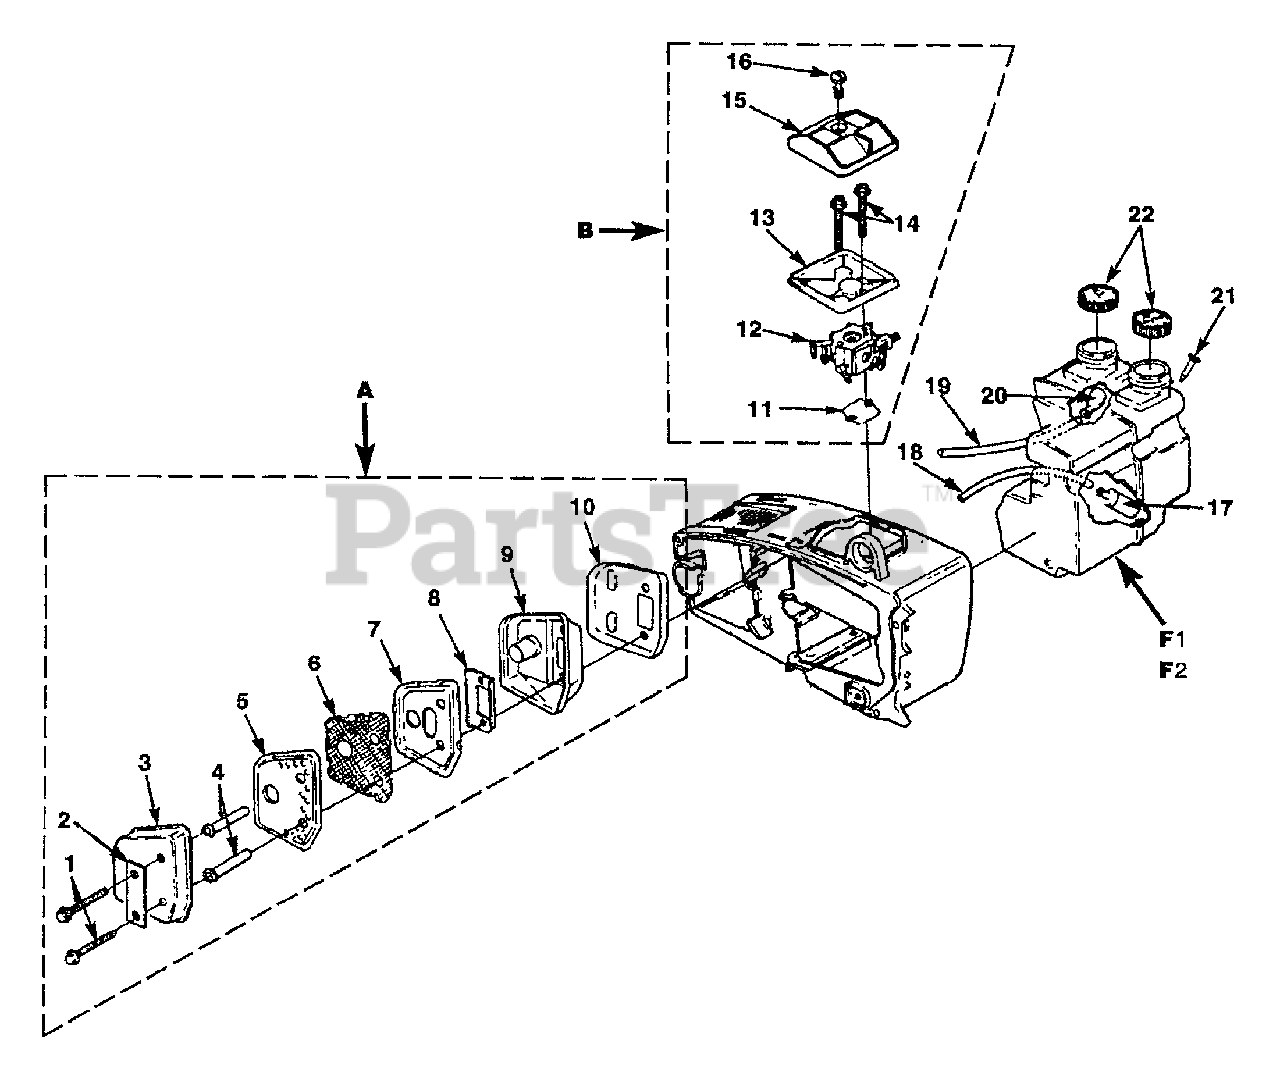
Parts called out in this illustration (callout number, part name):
1	SCREW-Mach. Sems Hex (10-24 x 2 1/16")
2	BRACKET-Muffler
3	CAP-Muffler
4	SPACER-Muffler
5	BAFFLE-Muffler
6	SCREEN-Spark Arrester
7	BAFFLE-Muffler
8	PLATE-Muffler
9	BODY-Muffler
10	DEFLECTOR-Exhaust
11	GASKET-Carburetor
13	CUP-Filter
14	SCREW-Mach. Hex (10-24 X 1 5/8")
15	FILTER ELEMENT (Top)
16	SCREW-Retaining
17	FILTER-Fuel
18	TUBING-Rubber (6 1/2")
19	TUBING-Rubber (7")
20	FILTER-Oil
21	VALVE-Duck Bill
22	CAP-Fuel & Oil
A	MUFFLER-Complete
B	CARBURETOR KIT
F1	TANK-Fuel & Oil
F2	TANK-Fuel & Oil (UT10635-C, UT10713, A; UT10715-A,B)
